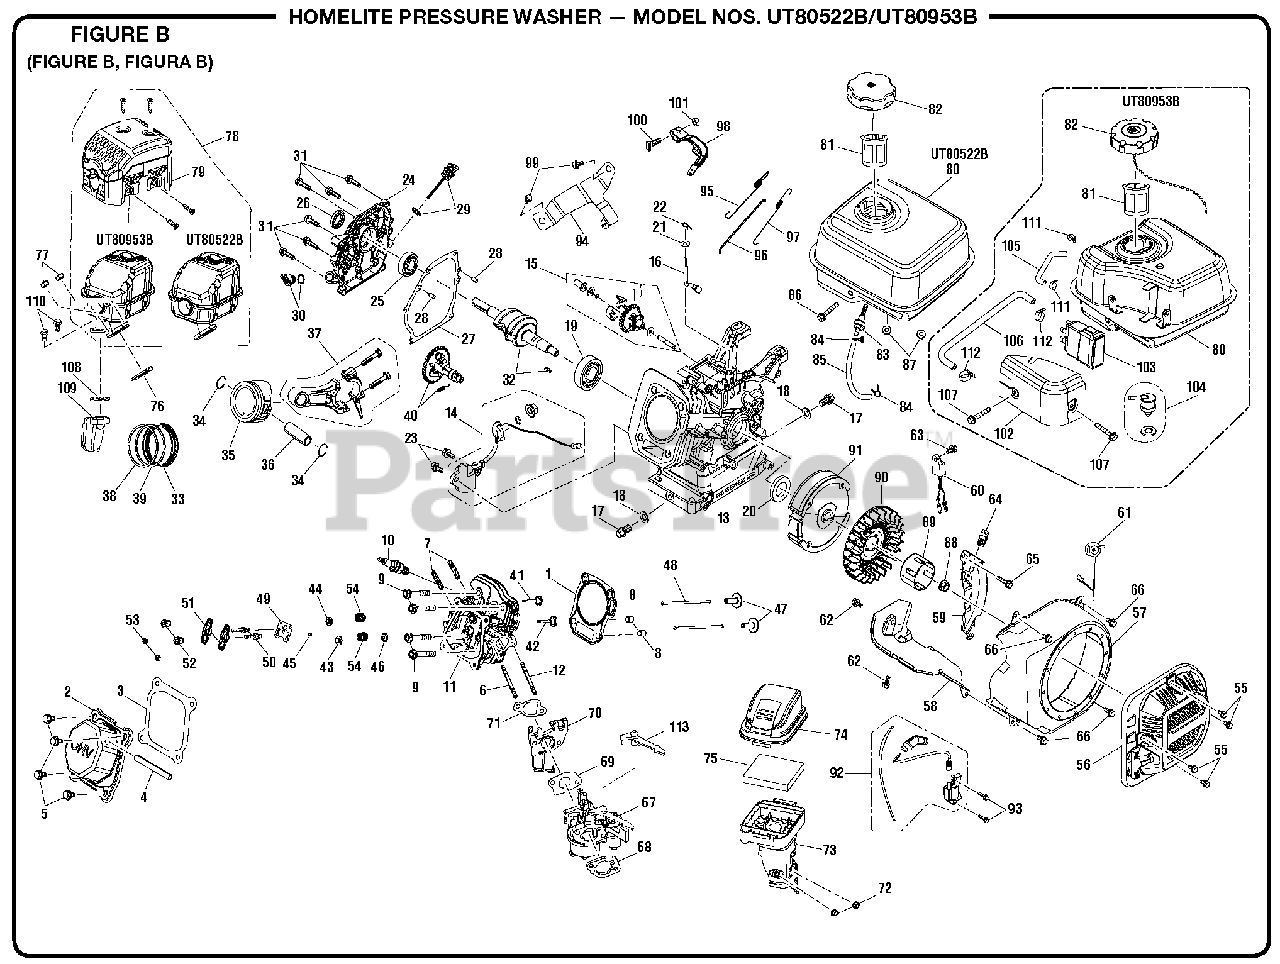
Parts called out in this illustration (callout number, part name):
1	Cylinder Head Gasket
2	Cylinder Head Cover Assembly
3	Cylinder Head Cover Gasket
4	Breather Tube
9	Cylinder Head Bolt
10	Spark Plug (Champion RC12YC)
11	Cylinder Head Assembly
13	Crankcase Assembly
14	Engine Oil Sensor
15	Governor Gear Assembly
16	Governor Arm
17	Drain Plug Bolt
21	Governor Gear Washer
24	Crankcase Cover Assembly
27	Crankcase Gasket
29	Oil Dipstick Assembly
30	Engine Oil Plug Assembly
32	Crankshaft Assembly
33	Oil Ring Set
34	Piston Pin Clip
35	Piston Assembly
37	Connecting Rod
39	Second Ring
40	Camshaft Assembly
41	Exhaust Valve
42	Intake Valve
43	Valve Spring Seat
44	Exhaust Valve Retainer
45	Valve Rotator
47	Valve Tappet
48	Valve Lifter
49	Lifter Stopper Plate Assembly
50	Valve Adjusting Bolt
51	Valve Rocker
52	Valve Adjusting Nut
53	Valve Lock Nut
54	Valve Spring
55	Bolt
56	Recoil Starter Assembly
58	Cylinder Body Shroud
59	Lower Shield
60	Oil Protector
61	Stop Engine Switch Assembly
67	Carburetor Assembly
68	Air Cleaner Gasket
69	Carburetor Gasket
70	Carburetor Insulator Plate
71	Carburetor Insulator Gasket
73	Air Cleaner
74	Air Cleaner Case Cover
75	Air Cleaner Element
76	Exhaust Outlet Gasket
78	Muffler Assembly
79	Muffler Outer Cover
80	Fuel Tank
81	Fuel Tank
82	Fuel Strainer
83	Fuel Tank Cap
84	Fuel Tank Cap
85	Fuel Tank Outlet Assembly
91	Starter Pulley
93	Flywheel Assembly
94	Ignition Coil
95	Ignition Coil
97	Throttle Control Assembly
98	Governor Spring
99	Governor Rod
100	Throttle Valve Return Spring
101	Governor Support Assembly
103	Governor Support Bolt
105	Canister Cover
106	Carbon Canister
107	Rollover Valve
108	Vapor Line
109	Vapor Line
110	Bolt
111	Air Valve Gasket
112	Muffler Air Valve
113	Bolt
